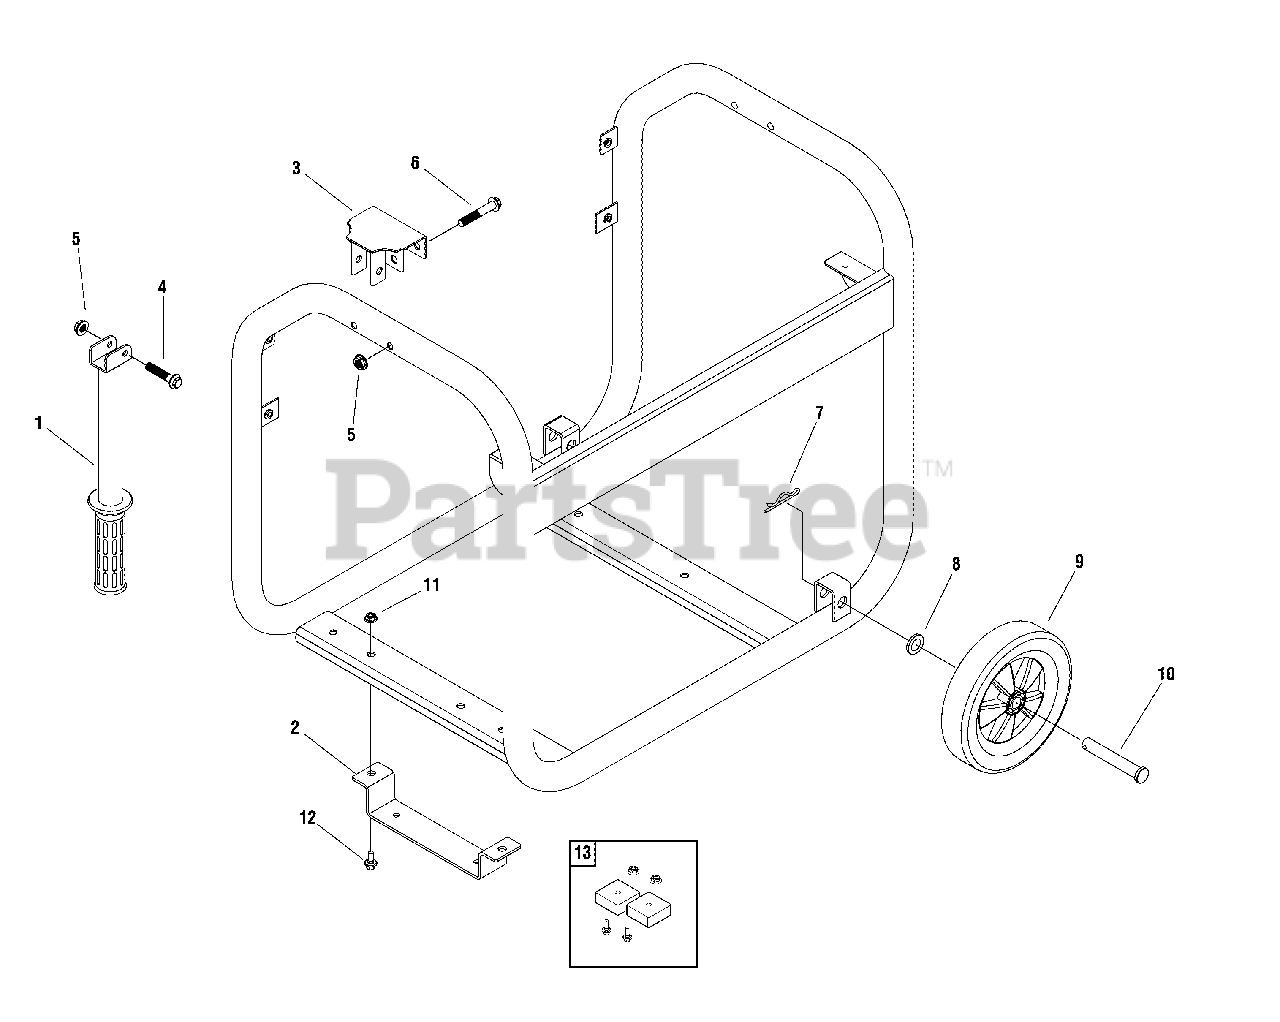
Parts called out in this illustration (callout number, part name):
4	* BOLT-M8 x 40
5	* NUT-FLANGE M8
6	* BOLT-M8 x 50
11	* NUT-FLANGE M6
12	* BOLT-M6 x 20
13	MOUNT-VIBRATION
